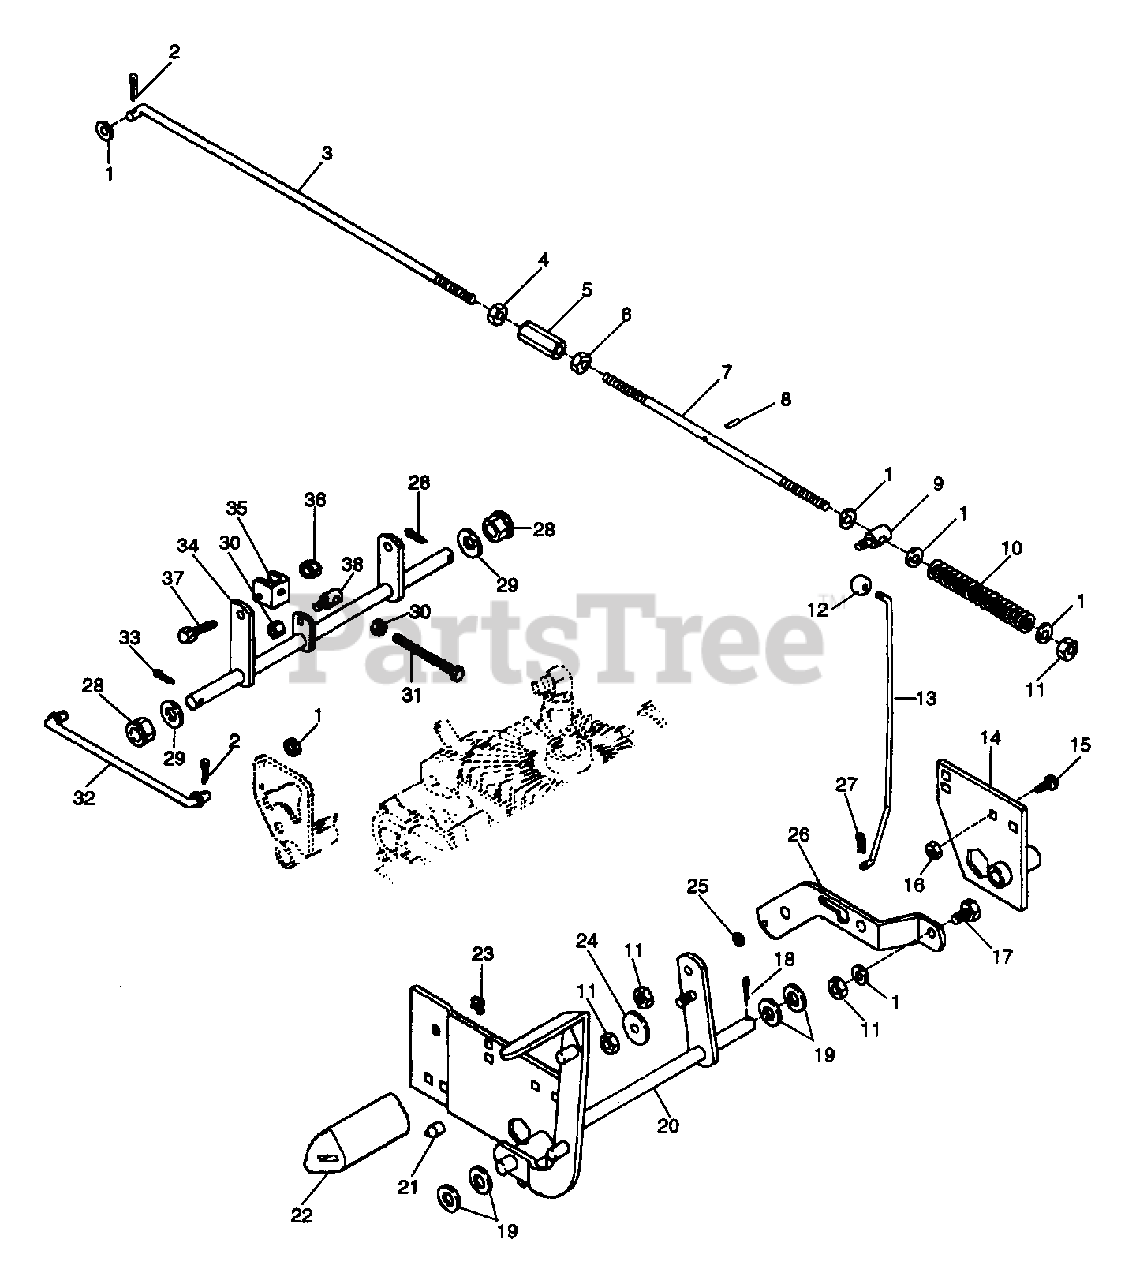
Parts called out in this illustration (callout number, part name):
1	WSHR-FL-STL.406X.812X.065PL
2	PIN-COTR .09X1.0 PL
3	BRAKE ROD
4	NUT LH THD .375-16 GR 2 PL
5	NUT-CUPLG RH & LH THD .37-16PL
6	NUT-HEX .375-16
7	BRAKE ROD
8	PIN-ROLL .125X.75
10	SG-COMP .125X.74X6.27 WLD 85
11	NUT-LK-CTR .375-16 GR A PL
12	PUSH/PULL CONTROL KNOB
13	BRAKE ROD-PARK
14	BRACKET
15	BLT-RDHDSQNK .31-18X.75 GR5 PL
16	NUT-FLG. .312-18 PL
17	BLT-HEX .38-16X.75 PL GR2
18	PIN-COTR .18X1.25 PL
19	WSHR-FL-STL .699X1.375X.059
20	BRAKE PEDAL
22	PEDAL COVER
23	SPIN DRIVE ZERK FITTING
24	WSHR-FL-STL .406X1.50X.049PL
25	WSHR-FL-STL .188X.438X.049 PL
26	ARM-PARK
27	PIN-COTR .06X.50
28	BSHG-FLG .625X.875X.750X1.19HX
29	WSHR-FL-STL.656X1.312X.095 PL
30	WSHR-FL-STL .755X2.000X.125
31	BLT-HEX .31-18X3.50 PL GR2
32	NEUTRAL ROD
33	@PIN-CTR .16X1.25 EXTPRSQCT YZ
34	BRAKE SHAFT
36	NUT-LK-CTR .250-20 PL
37	BLT-HEX .25-20X1.75 GR2
38	ROD PIVOT
